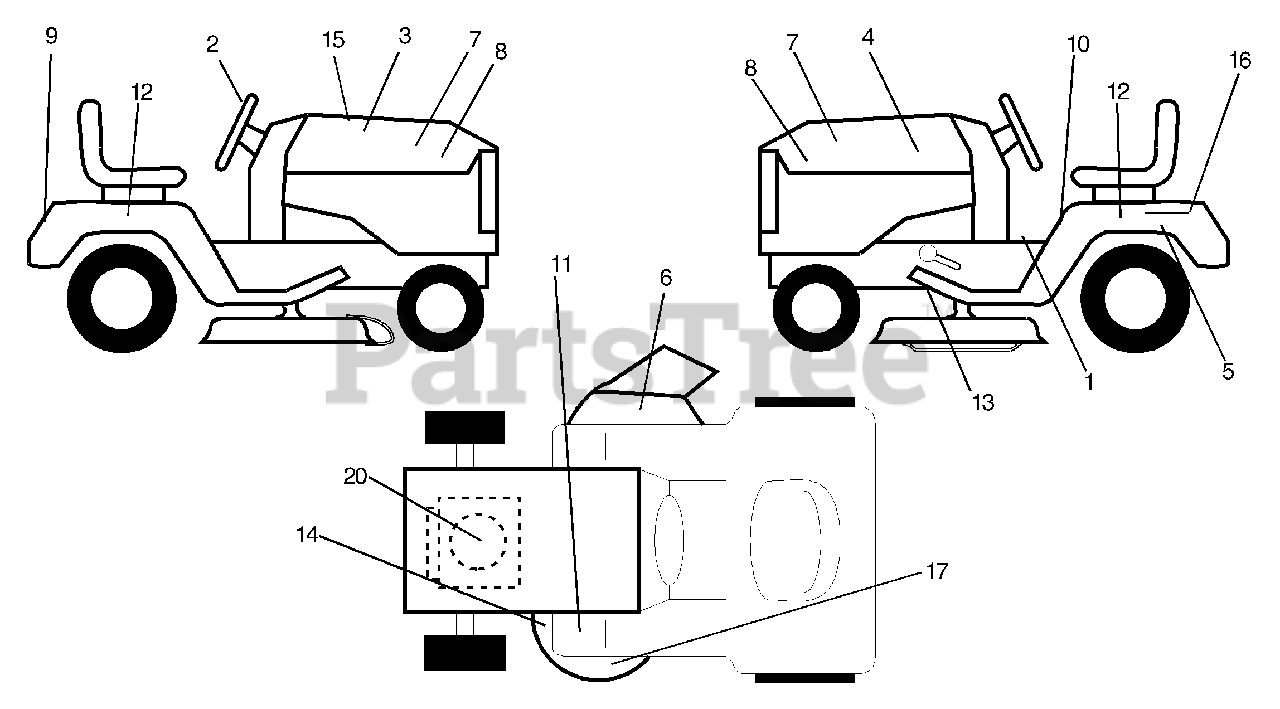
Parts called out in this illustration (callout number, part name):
1	Decal Instruction Operat English
2	Decal Ins Strg Wh
3	Decal Hood Rh
4	Decal Hood Lh
5	Decal Battery
6	Decal Warning Mower
7	Decal Panel Side
8	Decal Panel Side
9	Decal Fender Logo
10	Decal Danger English
11	Decal Clutch/brake English
12	Decal Fender Auto Rad
13	Decal V-Belt Drive Sch
14	Decal V-belt Schematic 42"
15	Decal Replacement Parts
16	Decal Battery Danger/Poison
17	Decal Deck Enviro
20	Decal HP Engine
